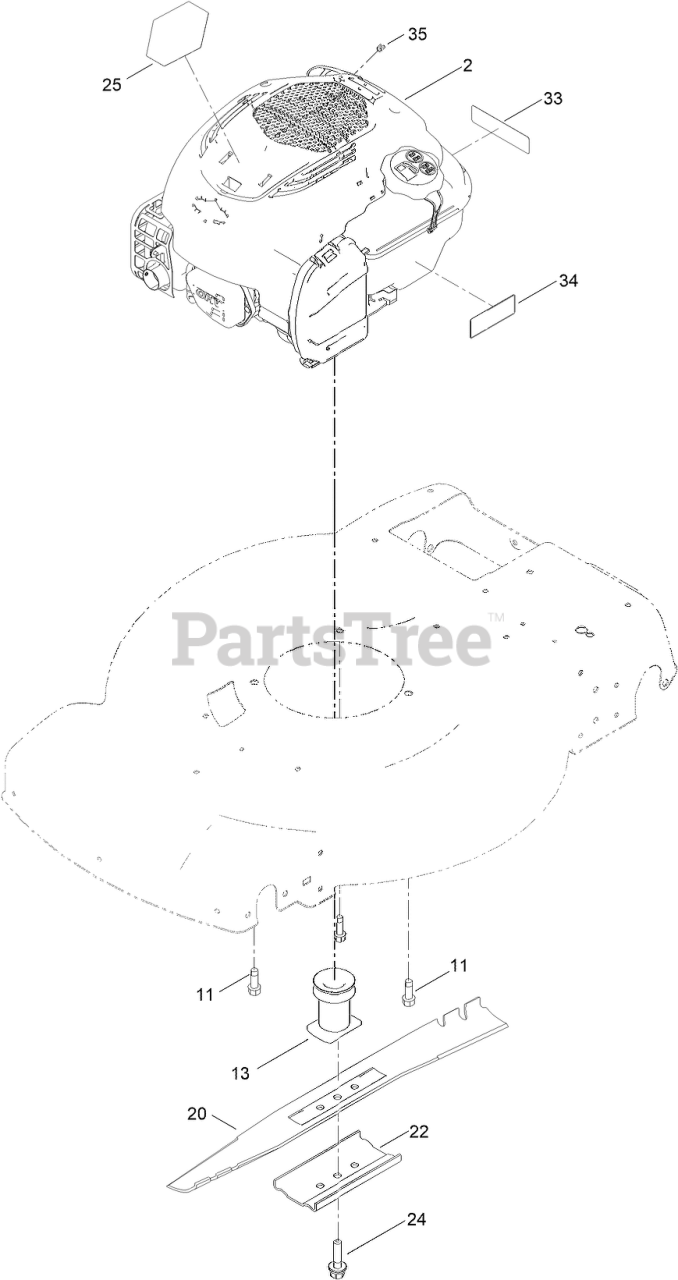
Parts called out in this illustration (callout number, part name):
11	SCREW-THD FORM, HWH
13	DRIVER-BLADE
20	BLADE-22 INCH
22	SUPPORT-BLADE
24	BOLT-BLADE
25	DECAL-BRIGGS 625 EXI SS
33	DECAL-ARRESTOR, SPARK
34	DECAL-LEVEL, FUEL
35	STOP-ROPE
